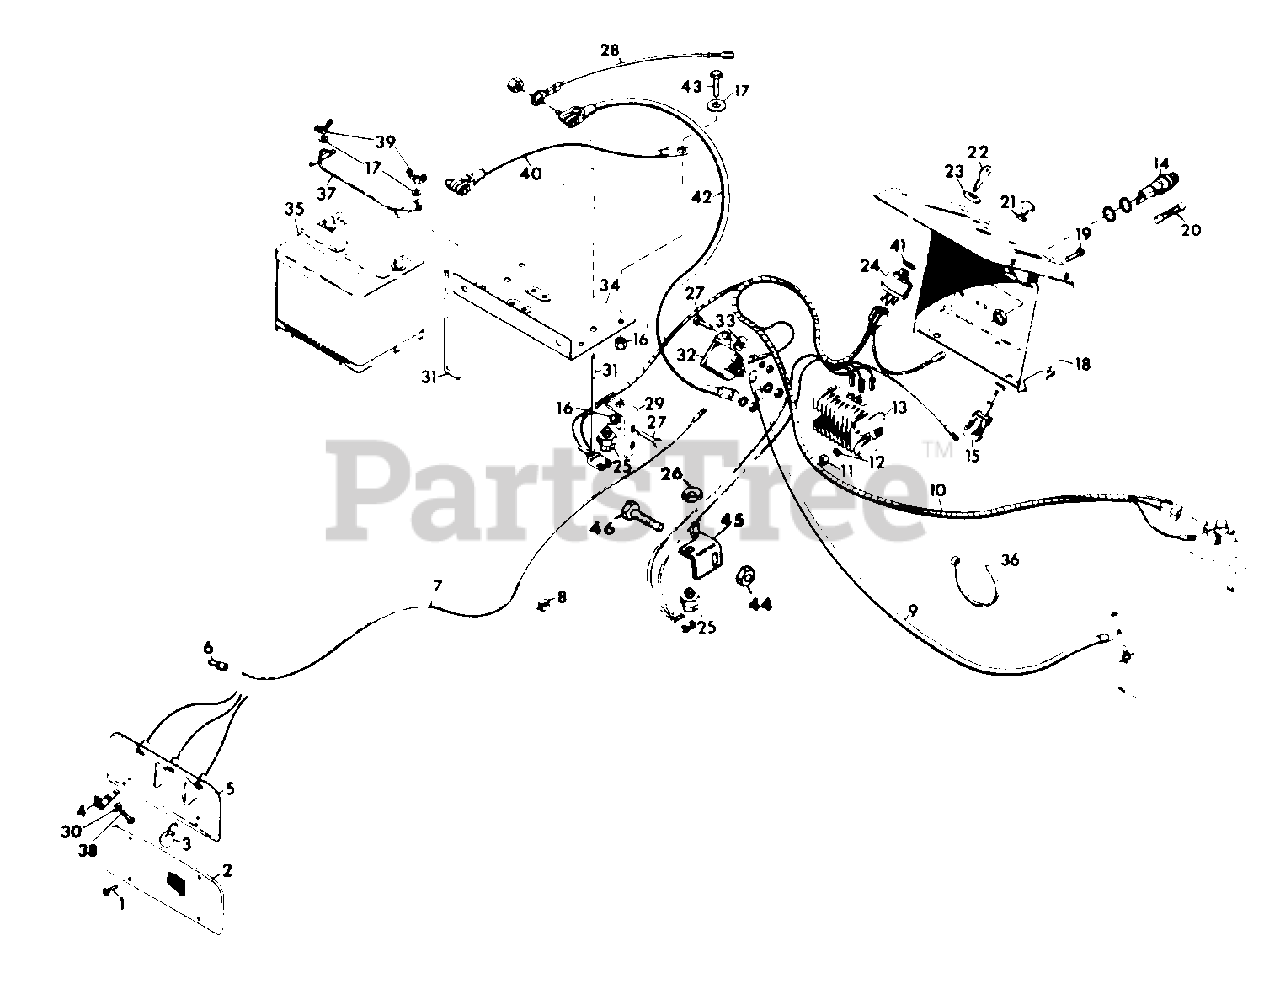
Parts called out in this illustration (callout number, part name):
1	SCREW, MACH, 10-24X.50 PAN HD C-RECESS
2	PANEL, FRONT LIGHT
3	LAMP, NO. 1073
4	CLIP, LIGHT MTG.
5	ASSEMBLY, LAMP REFLECTOR
6	NUT, WIRE
7	WIRE, HEADLIGHT
8	CLIP, WIRE
9	CABLE, STARTER
10	HARNESS, WIRING 12 HP KOHLER
11	NUT, HEX, 1/4-20
12	WASHER, LOCK 1/4 SP
13	REGULATOR, RECTIFIER
14	FUSE, PANEL
15	SWITCH, LIGHT
16	NUT, LOCK 1/4-20
17	WASHER, FLAT .281X.625X.065
18	PANEL INSTRUMENT
19	SCREW, MACHINE 1/4-20 PAN HD
20	FUSE, 30 AMP ACC-30
21	NUT, SPECIAL, LIGHT SWITCH
22	KEY, IGNITION SWITCH
23	NUT, JAM 9/16-24
24	SWITCH, IGNITION
25	SWITCH, INTERLOCK
26	NUT, STAMPED, 9/16-18
27	BOLT, HEX, 1/4-20X.625
28	WIRE, INSTRUMENT PANEL
29	BRACKET, SWITCH
30	WASHER, FLAT .188X.562X.049
31	HOOK, BATTERY
32	SWITCH, MAG.
33	NUT, SPEED, 1/4-20
34	TRAY, BATTERY
35	BATTERY, 12V
36	TIE, CABLE
37	BRACKET, BATTERY HOLD DOWN
38	SCREW, MACH. 10-24X.75 PAN HD C-RECESS
39	NUT, WING, 1/4-20 WASHER INSERT
40	CABLE, NEGATIVE BATTERY
41	WASHER, LOCK 9/16 INT. TOOTH
42	CABLE, BATTERY TO MAGNETIC SWITCH
43	BOLT, HEX 1/4-20X.875
44	NUT, LOCK 3/8-16
45	BRACKET, INTERLOCK SWITCH
46	BOLT, HEX 3/8-16X1.25
NS	BOOT, BATTERY CABLE
NS	WASHER, LOCK 1/4 EXT TOOTH TYPE A
